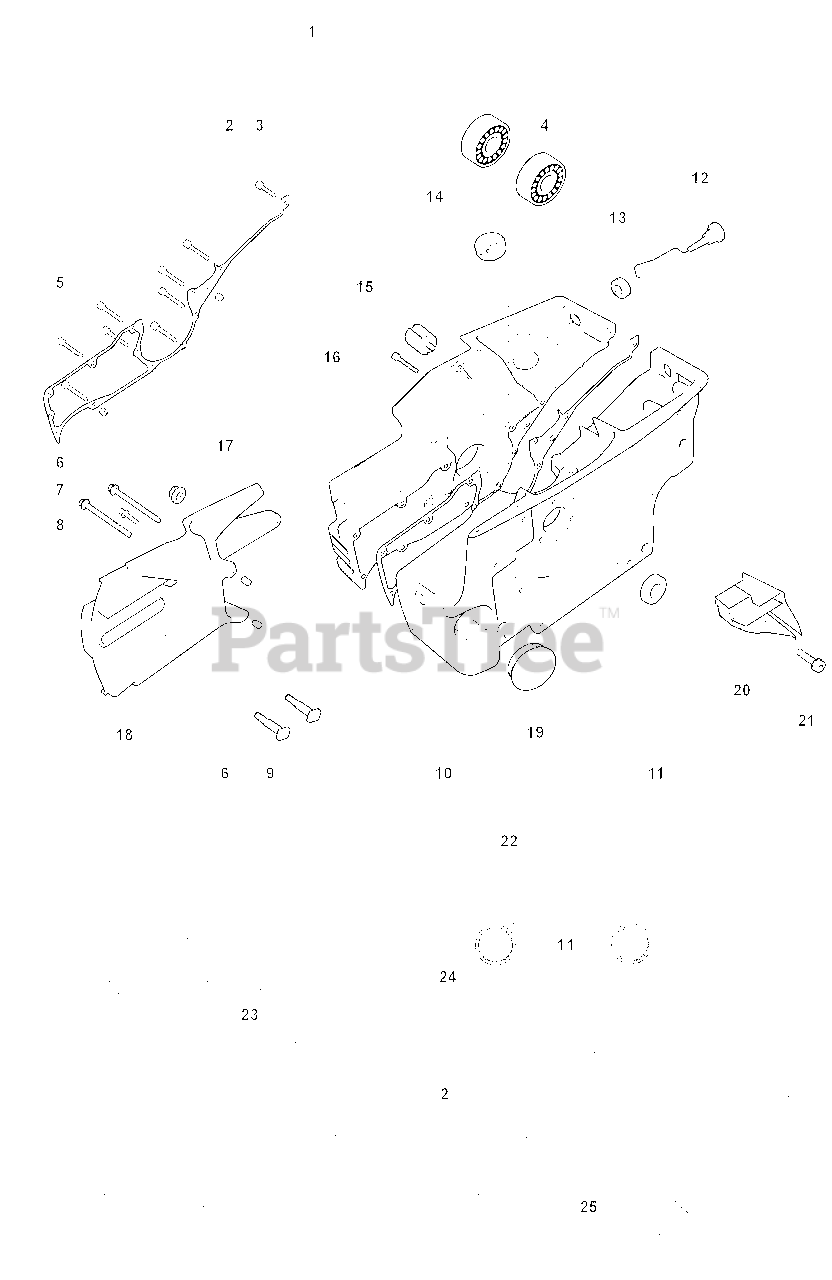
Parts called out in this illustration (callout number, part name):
1	CRANKCASE
2	CRANKCASE GASKET
3	SCREW
4	BALL BEARING
5	SCREW
6	GUIDE BUSHING
11	SEALING RING
12	CHOKE CONTROL
15	VIB.INSULATOR
17	NUT FLANGE
18	CUTTER ARM
20	AIR NOZZLE
21	SCREW
22	GASKET KIT
23	GASKET
24	GASKET MUFFLER
